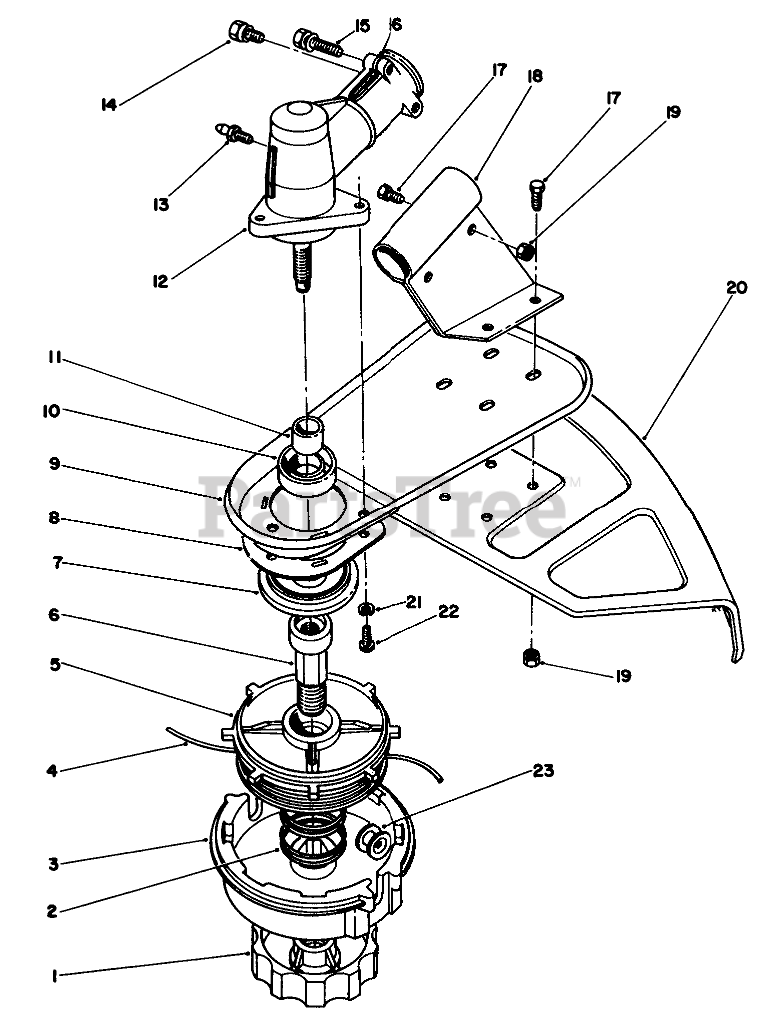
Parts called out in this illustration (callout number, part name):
1	LH KNOB(SERVICE ONLY)
2	SPRING (SERVICE)
3	SPOOL HSG (SERVICE ONLY
4	REPL LINE PKG
5	INNER SPOOL(SERV ONLY)
6	SHAFT (SERVICE ONLY)
7	DUST CAP F/W
8	GRASS WRAP GUARD
9	SHIELD SUPPORT R
10	OIL SEAL
11	SPLINED SLEEVE
12	Gear Box Assembly (Incl. Ref. #10, 11, & 13-15)
14	HHMS SCREW
15	HHMS SCREW
16	WASHER
17	SCREW-SHH
18	Bracket-Shield
19	NUT-LOCK, NI
20	GRASS SHIELD-STEEL
21	LOCKWASHER
22	SCREW
23	EYELET(SERVICE)
